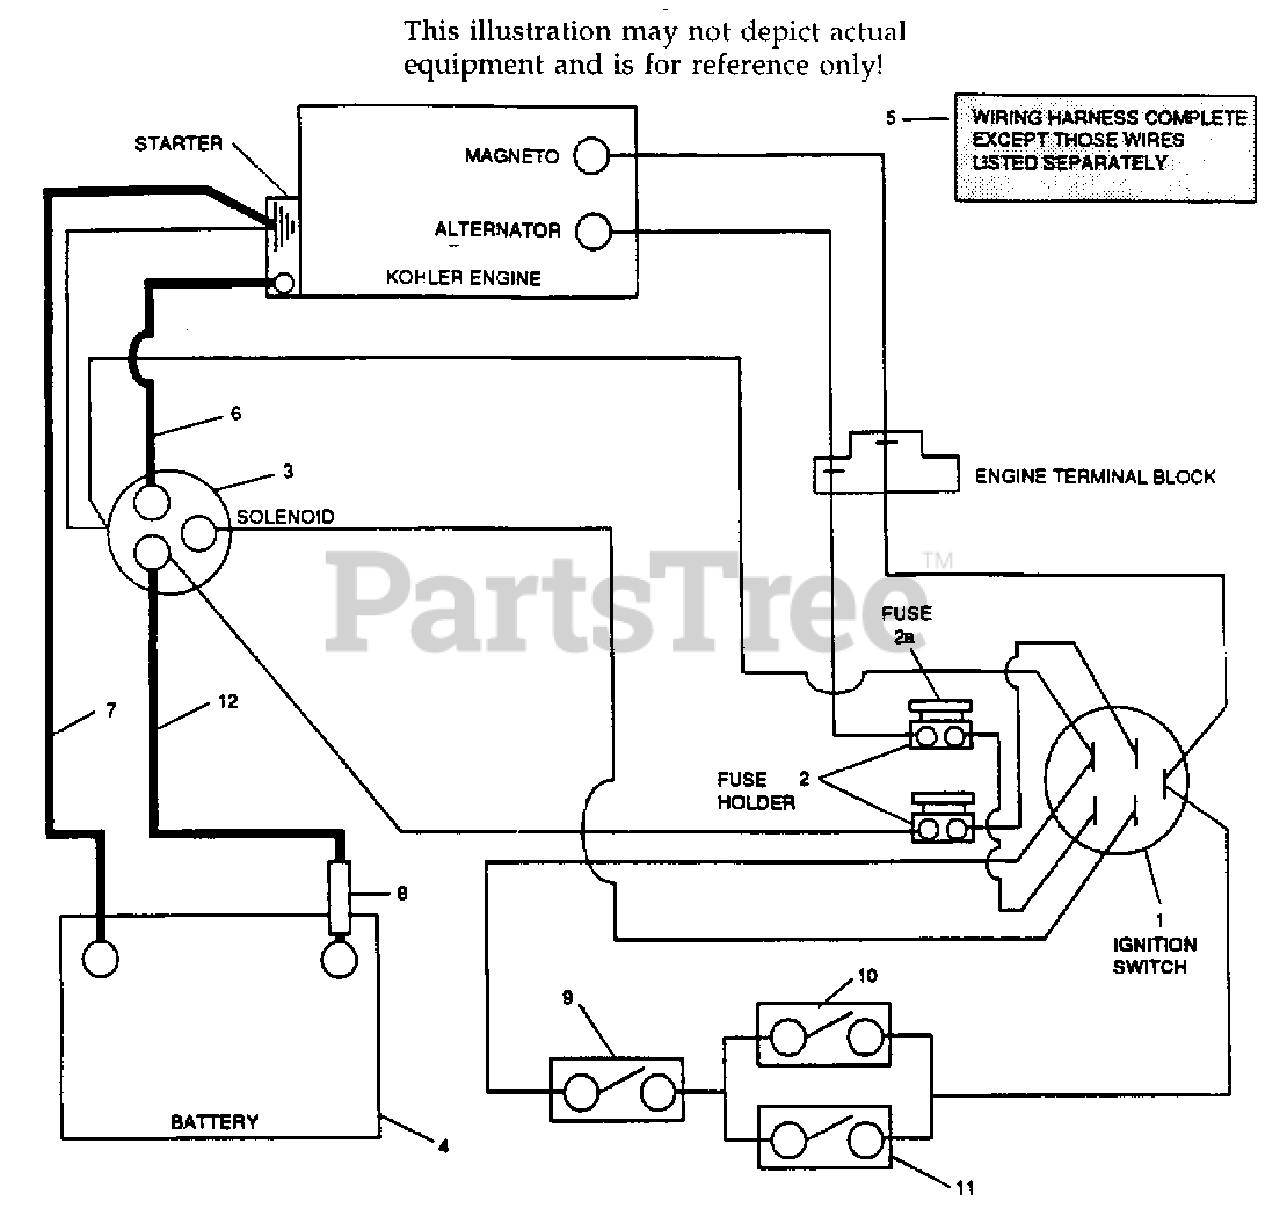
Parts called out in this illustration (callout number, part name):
1	KEY SWITCH
2	FUSE HOLDER
2A	FUSE 20 AMPS
3	SOLENOID
4	BATTERY MAY BE PURCHASED LOCALLY(U9-LM)
5	WIRING HARNESS COMPLETE
6	BATTERY CABLE - 13-3/4" RED
7	BATTERY CABLE - 20" BLACK
8	RUBBER BOOT
9	SWITCH, HANDLE INTERLOCK N.C.
10	SWITCH, CUTTER DRIVE INTERLOCK N.C.
11	SWITCH, NEUTRAL INTERLOCK N.O.
12	BATTERY CABLE - 31.5" RED
